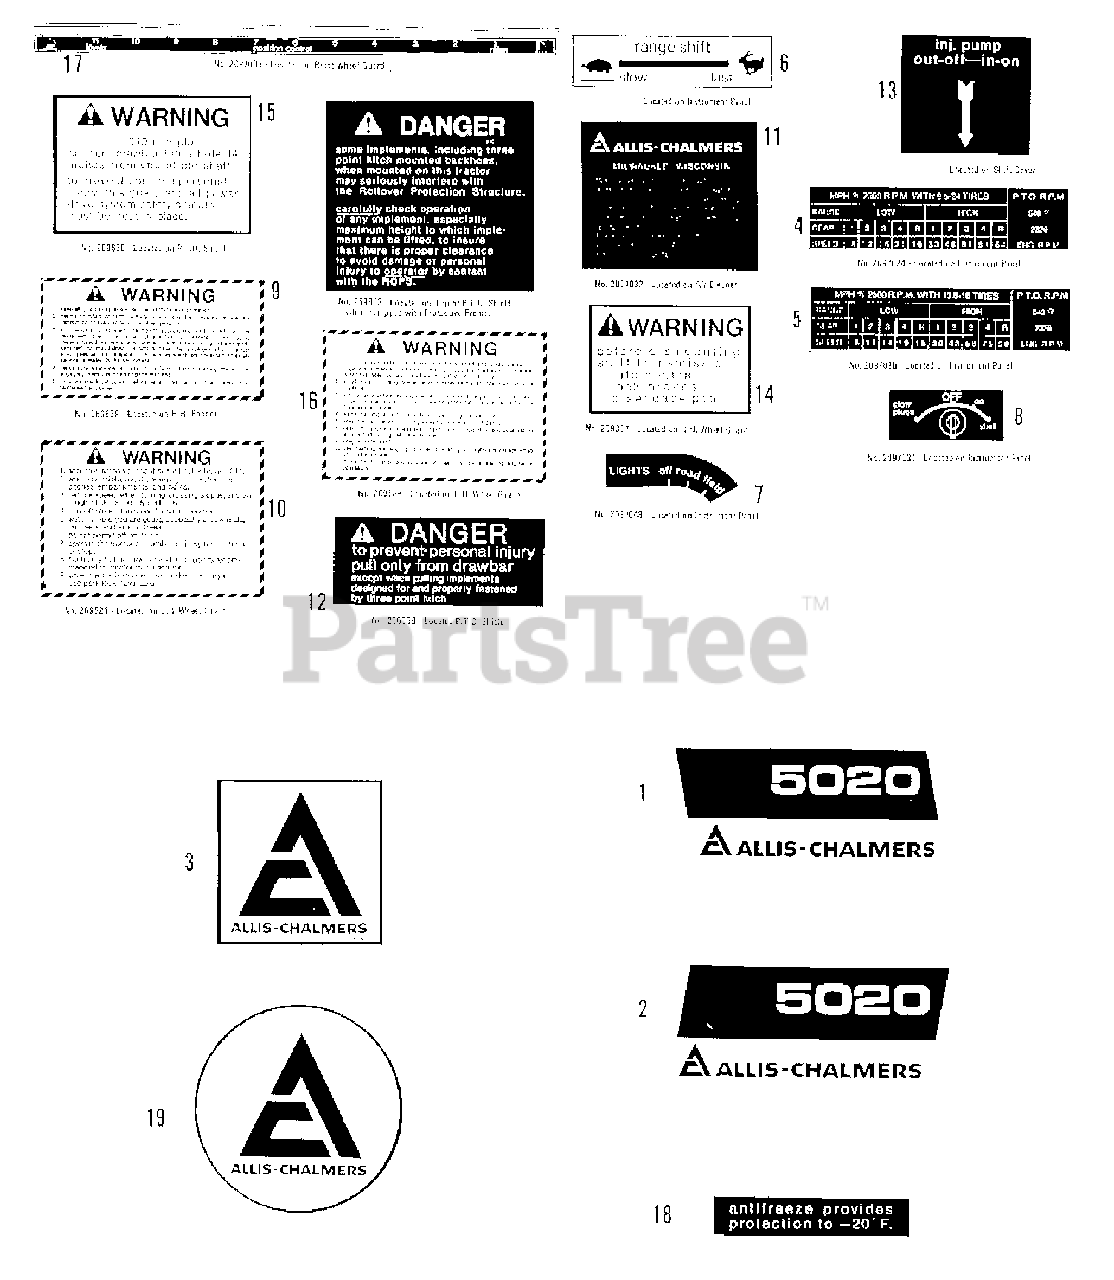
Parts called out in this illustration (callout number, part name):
1	DECAL, model design L.H.
2	DECAL, model design R.H.
3	DECAL, A-C trademark
4	DECAL, speed (w/9.5-24 Tires)
5	DECAL, speed (turf)
6	DECAL, range shift
7	DECAL, lights
8	DECAL, starter switch
9	DECAL, warning
10	DECAL, warning
11	DECAL, air cleaner
12	DECAL, danger (P.T.O. shield)
13	DECAL, injection pump
14	DECAL, dismounting instr.
15	DECAL, warning (P.T.O. shield)
16	DECAL, warning
17	DECAL, (Pos. Control)
18	DECAL, antifreeze
19	DECAL, A-C trademark, steering wheel
